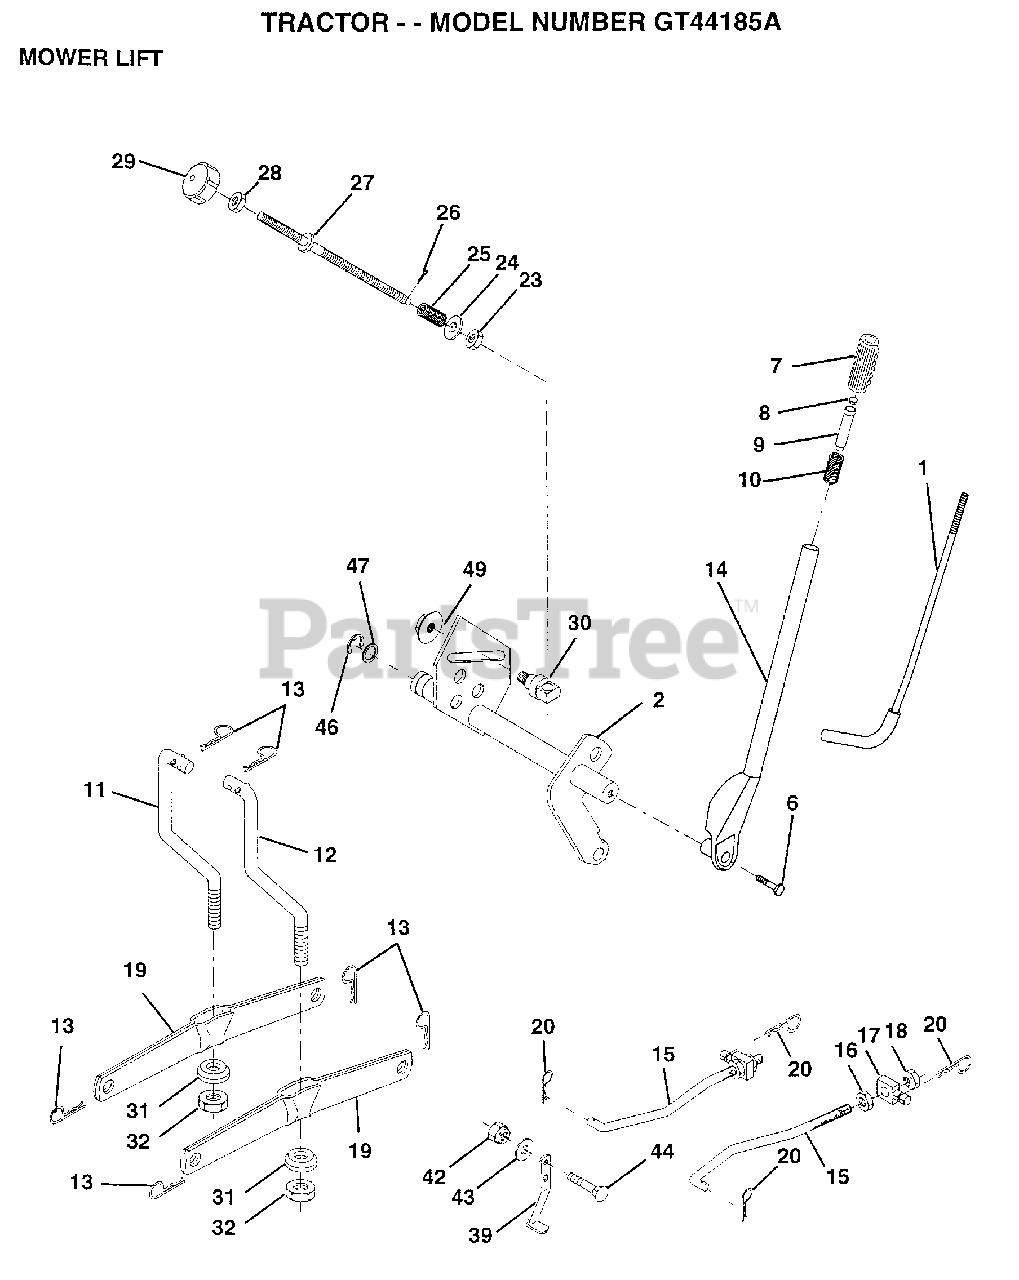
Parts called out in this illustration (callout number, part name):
1	LEVER ROD LT
2	SHAFT LIFT W/IND
6	"BOLT,HEX"
7	GRIP
10	SPRING T
11	LINK.LIFT.LH.GTV
12	LINK.LIFT.RH.GTV.
15	LINK.FRONT
16	NUT
17	TRUNION
18	NUT.LK.W/WSH.1/2.
19	ARM SUSP REAR
20	RETAINER.SPRING
23	NUT T
24	WASHER
25	SPRING.COMP.INF.H
27	ROD.ADJ.LIFT
28	NUT
29	KNOB INF 3/8-16
30	TRUNNION
31	BEARING PVT LH
32	NUT.CROWNLOCK.3/8
39	STOP.OVER.CENTER
43	WASHER GT
44	BOLT
46	E-RING
47	WASHER
49	NUT.HXFLG.LOCK.
